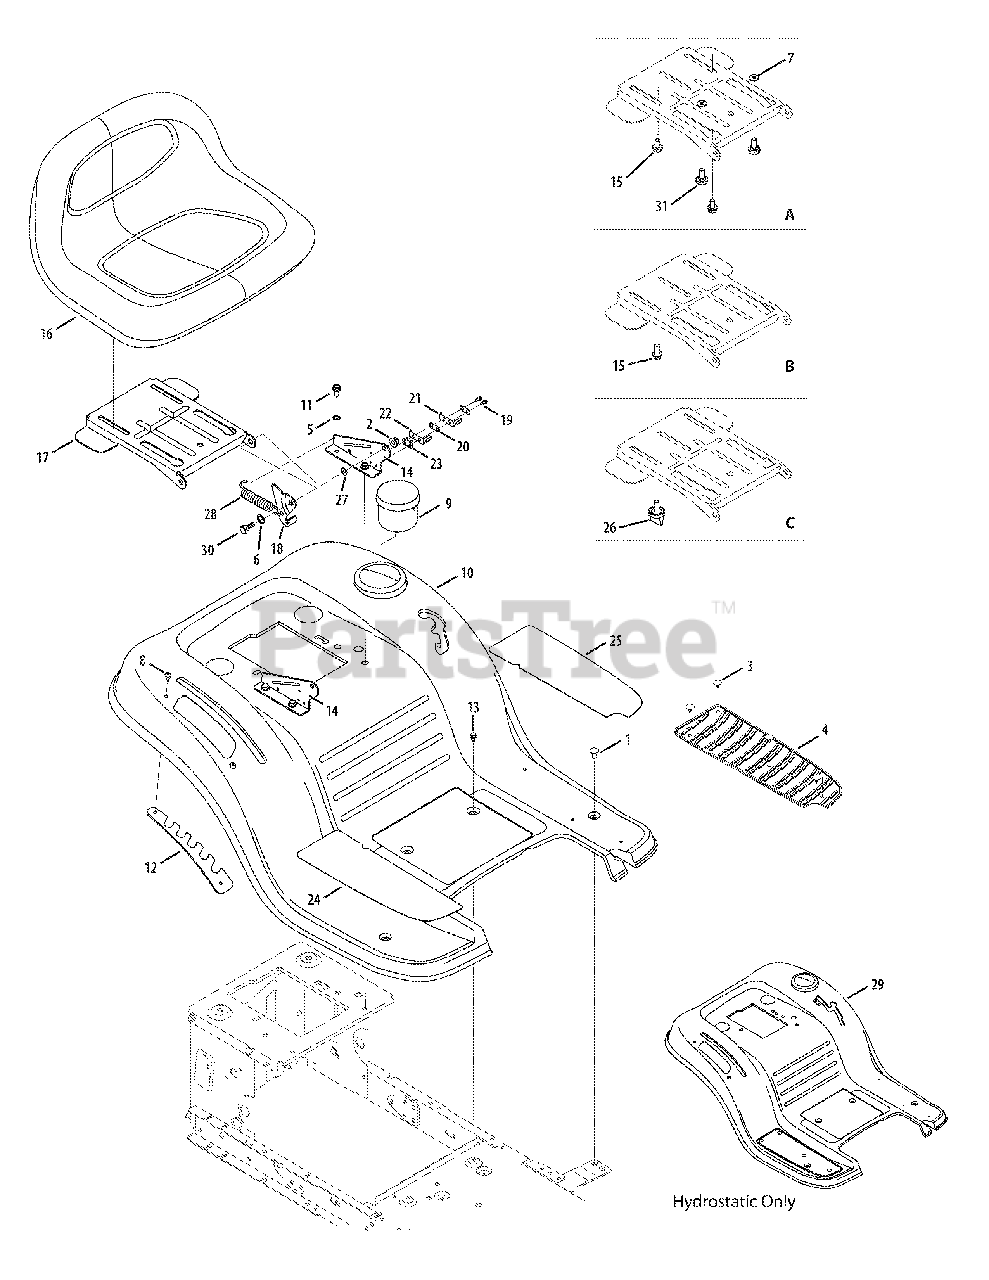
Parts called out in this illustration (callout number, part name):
1	Carriage Bolt 1/4-20 x .62
2	Flange Locknut 5/16-18 Gr. F, Nylon
3	Ratchet Clip
4	Foot Pad, RH
4	Foot Pad, LH
5	Lockwasher 5/16 ID
6	Flat Washer .510 x .750 x .033
7	Flat Washer .405 x .875 x .059
7	Flat Washer .395 x .62 x .063
8	Screw, 1/4-20 x .50
9	Cup Holder
10	Fender
11	S-Tapp Scr 5/16-18 x .75
12	Lift Adjustment Bracket
13	Hex Wash S-Tapp Scr 1/4-20 x .50
14	Seat Mounting Bracket
15	Screw 3/8-16 x .875
16	Seat, Low Back
17	Seat Pivot Bracket
18	Seat Lift Bracket
19	Hex Wash HD AB S-Tapp Scr #8-.50
20	Insulator Plate
21	Spring Switch
22	Seat Spring Switch
23	Insulator Plate
24	Foot Pad, Abra sive, RH
25	Foot Pad, Abra sive, LH
27	Push Speed Nut
28	Extension Spring .84 Dia. x 4.6
29	Fender - Hydrostatic
30	Shoulder Screw
31	Shoulder Screw .625 x .175, 3/8-16
